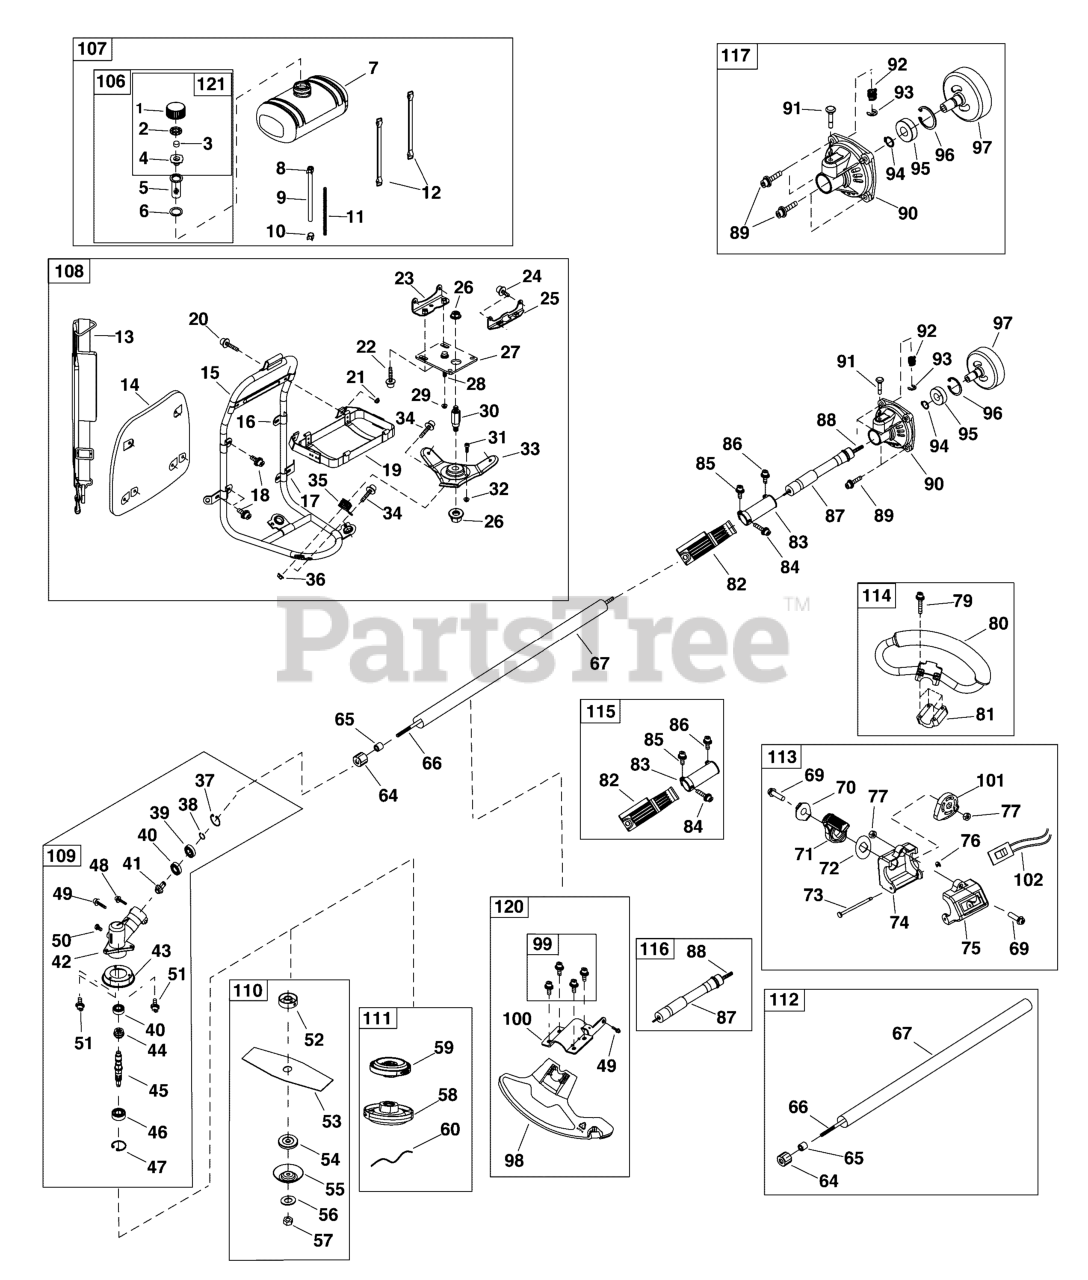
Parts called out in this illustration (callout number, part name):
1	CAP, Fuel Tank
2	INNER CAP, Fuel Tank
3	NET, Fuel Filter
4	INNER CAP, Rubber
5	FUEL FILTER ASSEMBLY
6	GASKET, Filter
7	FUEL TANK
8	CLAMP, Fuel Hose, Upper
9	FUEL PIPE
10	CLAMP, Fuel Hose, Lower
11	SPRING, Fuel Pipe Protection
12	BELT, Fuel Tank
14	CUSHION, Back
15	BRACKET, Engine
16	BRACKET, Back Cushion, Upper
17	BRACKET, Back Cushion, Lower
18	BOLT, M5 x 16
19	BRACKET ASSEMBLY, Fuel Tank
21	NUT, M5
22	BOLT, M6 x 16
23	BRACKET, Front
24	BOLT, M5 x 16
25	BRACKET, Rear
26	NUT, M10
27	PLATE, Bracket
28	BOLT, M6 x 40
29	NUT, M6
31	BOLT, M5 x 12
32	NUT, M5
33	SEAT ASSEMBLY
34	BOLT, M6 x 16
35	SPRING
36	NUT, M6
39	BEARING
41	PINION
42	CASE, Gear Box
43	COVER, Blade
45	SPLINE SHAFT
46	BEARING
50	BOLT, M6 x 12
51	BOLT, M5 x 10
52	GASKET, Spline
53	BLADE, Two Teeth
54	HOLDER
55	PROTECTOR, Blade
56	WASHER, Wave, Dia 10
58	BUMP HEAD BOX
59	COVER, Alloy Head
60	TRIMMER LINE (10 Pack)
64	COVER, Drive Shaft, Rubber
65	OIL BEARING
66	DRIVE SHAFT
67	SHAFT, Straight, BP Brusch
70	* WASHER
71	LEVEL, Throttle, Red
74	THROTTLE COVER, Rear
75	THROTTLE COVER, Front
76	STOP RING. 2.5
79	BOLT, M5 x 35
80	HANDLE
81	HOLDER, Lower
82	COVER, Shaft Connection
83	CONNECTOR, Straight Shaft
85	BOLT, M5 x 20
86	BOLT, M5 x 30
87	SHAFT, Flexible, Outer
88	SHAFT, Flexible, Inner
89	BOLT, M6 x 20
90	CASE, Clutch
92	SPRING
93	STOP RING, 5
97	CLUTCH DRUM, Comp.
98	SAFETY GUARD
99	BOLT, M5 x 10
100	HOLDER, Safety
101	SEAT, Throttle Control
102	SWITCH, Stop, Red
106	KIT, Fuel Cap Assembly
107	KIT, Fuel Tank Assembly
108	KIT, Back Belt Group
109	KIT, Gear Box Assembly
110	KIT, Blade Assembly
111	KIT, Alloy Head
112	KIT, Drive Shaft Assembly
113	KIT, Throttle Assembly
114	KIT, Front Handle
115	KIT, Shaft Connection, Group
116	SHAFT ASSEMBLY, Flexible
117	KIT, Clutch Assembly
120	KIT, Safety Guard
121	LID, Fuel Tank, Comp.
